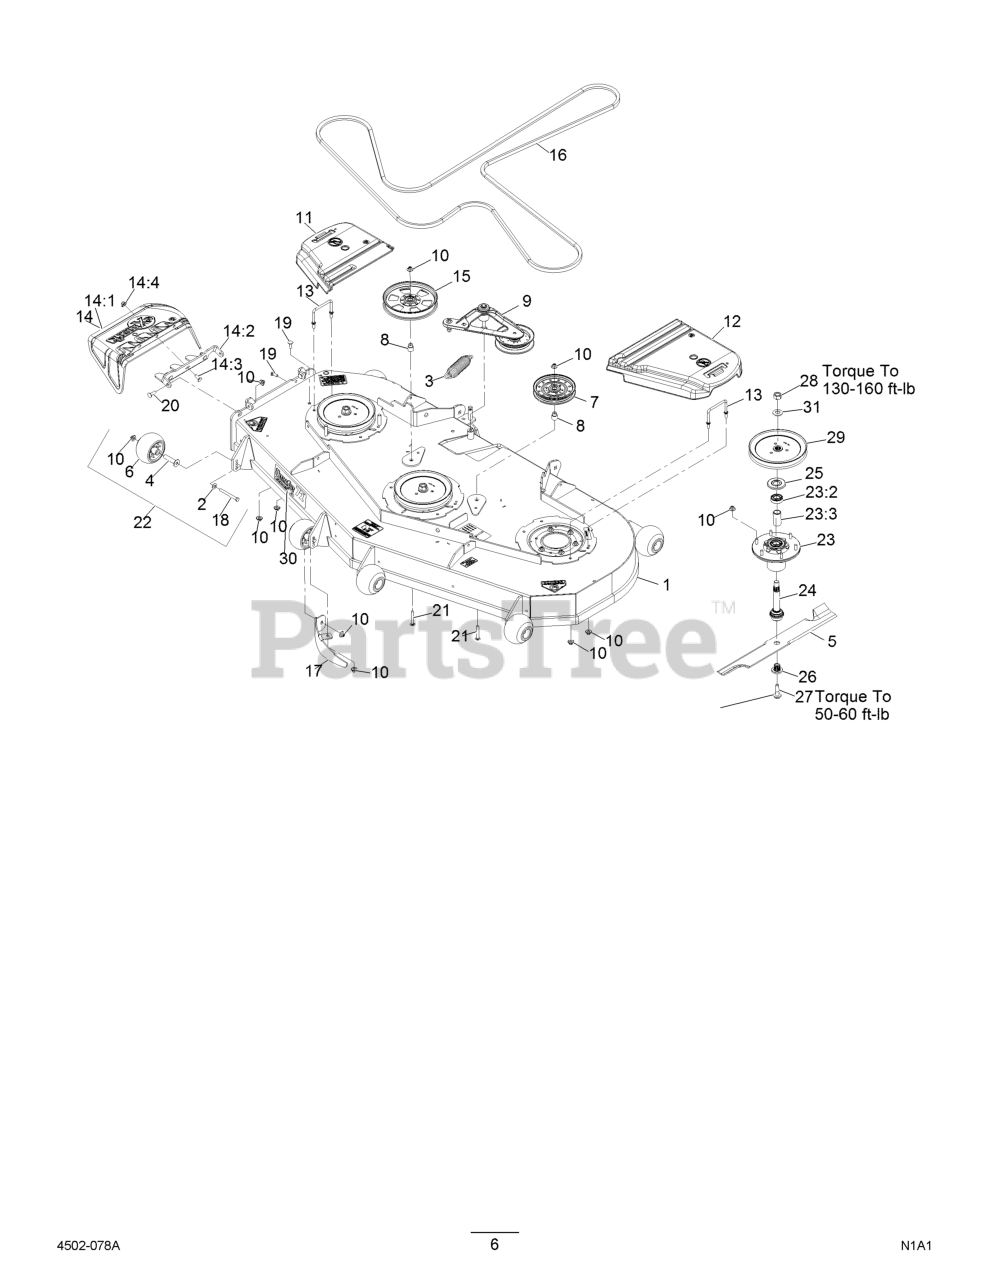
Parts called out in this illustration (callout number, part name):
1	ASM,DECK W/DECALS 724
2	WASHER-BELLEVILLE
3	SPRING-EXTENSION
4	AXLE, ROLLER
6	ROLLER-SCALP, ANTI
8	BUSHING-IDLER
9	DECK IDLER ASM
10	Nut-Nyloc 3/8-16 Flg
11	COVER-BELT, RH
12	COVER-BELT, LH
13	WIREFORM-COVER
14	ASM,DISCHARGE CHUTE
14:	Nut-Nyloc 3/8-16 Flg
14:1	CHUTE,DISCHARGE
14:2	BRACKET,DISCHARGE CHUTE
14:3	SCREW-CARR
15	PULLEY-IDLER, FLAT
16	BELT-V
17	BAFFLE-DOGLEG, LZ72
18	SCREW-HH 3/8-16 X 3 3/4 GR 8
19	SCREW-CARR
20	Bolt-Carriage 3/8-16 X 1 1/4
21	SCREW-CARR
22	KIT, ANTI-SCALP ROLLER
23	ASM-CUTTER HSG WITH BEARINGS
23:2	BEARING-BALL
23:3	SPACER-BEARING
24	ASM-SPINDLE AND SEAL
25	GUARD,BEARING TOP .989
26	BUSHING,SPLINED
27	SCREW,SEMS 1/2-20 X 2.19
28	NUT-HEX
29	SHEAVE,BLADE DRIVE 8.74
30	DECAL,ULTRACUT 72 SERIES
